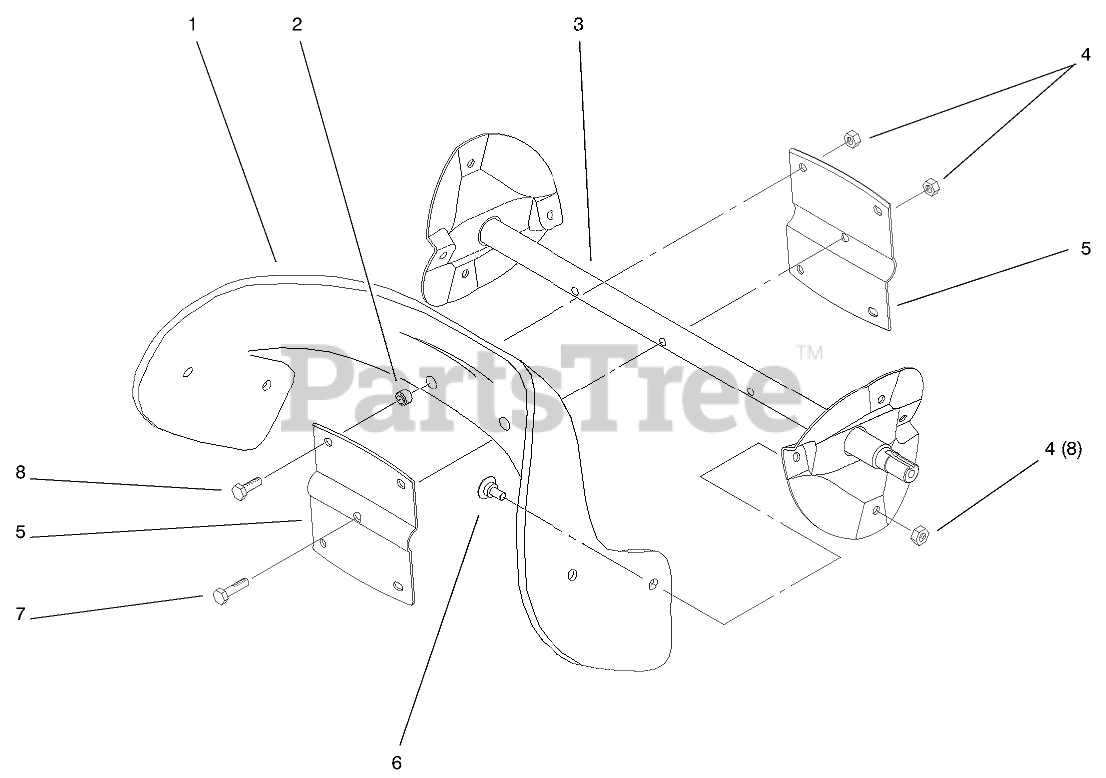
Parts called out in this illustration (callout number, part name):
1	BLADE-ROTOR
2	SPACER-BLADE, ROTOR
3	Rotor
4	NUT-LOCK, NI
5	HALF-ROTOR
6	SCREW
7	SCREW-HH
8	SCREW-HH
